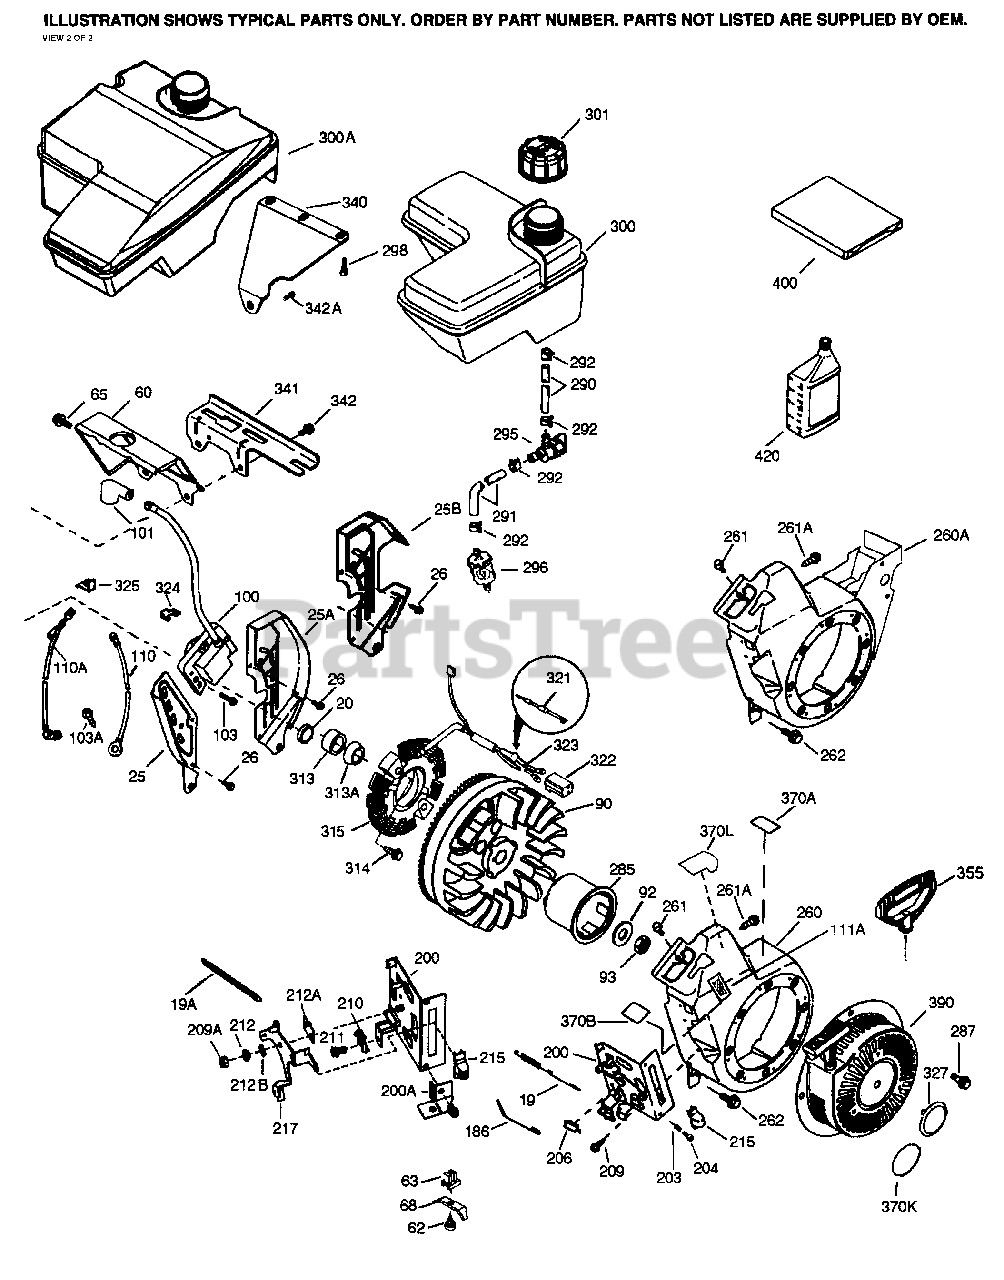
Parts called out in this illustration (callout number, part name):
19	Extension Spring
20	Oil Seal
25	Air Baffle (Left)
25A	Air Baffle (Right)
26	Screw, 10-24 x 9/16"
45	Connecting Rod Ass'y (Incl. 46 & 49)
60	Blower Housing Extension
65	Screw, 10-24 x 9/16"
90	Flywheel
92	Belleville Washer
93	Flywheel Nut
100	Solid State Ignition
101	Spark Plug Cover
103	Screw, Torx T-15, 10-24 x 15/16"
110	Ground Wire
186	Governor Link
200	Control Bracket (Incl. 206 & 215)
206	Terminal
209	Screw, 10-32 x 1/2"
215	Control Knob
260	Blower Housing
261	Screw, 1/4-20 x 31/64"
261A	Screw, 10-32 x 1/2"
262	Screw, 1/4-20 x 31/64"
285	Starter Cup
287	Screw, 1/4-20 x 31/64"
290	Fuel Line
292	Fuel Line Clamp
298	Screw, 1/4-15 x 3/4"
300A	Fuel Tank (Incl. 292 & 301) (4 Quart)
301	Fuel Cap
325	Wire Clip
340	Fuel Tank Bracket (Upper)
341	Fuel Tank Bracket (Lower)
342	Screw, 1/4-20 x 7/8"
342A	Screw, 1/4-20 x 5/8"
370A	Lubrication Decal
370B	Speed Control Decal
370K	Starter Decal
390	Rewind Starter NOTE: This engine cou ld have been built with 590746 starte r.
400	* Gasket Set (Incl. items marked PK in notes) Incl. (1) each of 26756,27272A , 29673, 35626, 36581, 36624,36719
420	SAE 30 4-Cycle Engine Oil (Quart)
999	Summer Maintenance Kit (incl. Oil, Sp ark Plug, Air Cleaner, & Ultra Fresh)
